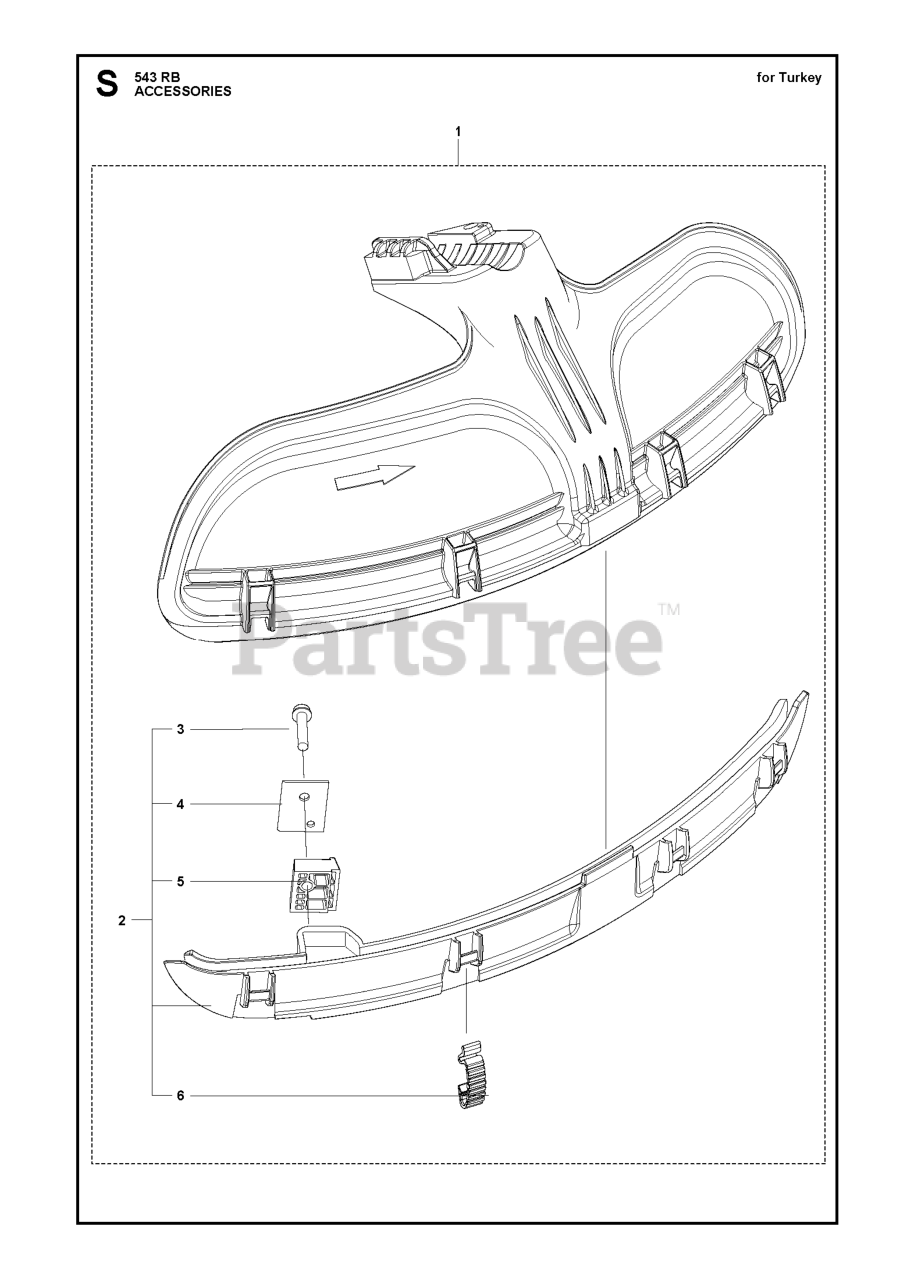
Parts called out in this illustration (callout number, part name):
1	COMBI PROTECTOR
2	SPLASH GUARD
3	SCREW
4	LINE CUTTER
5	DISTANSBLOCK
6	BUCKLE
